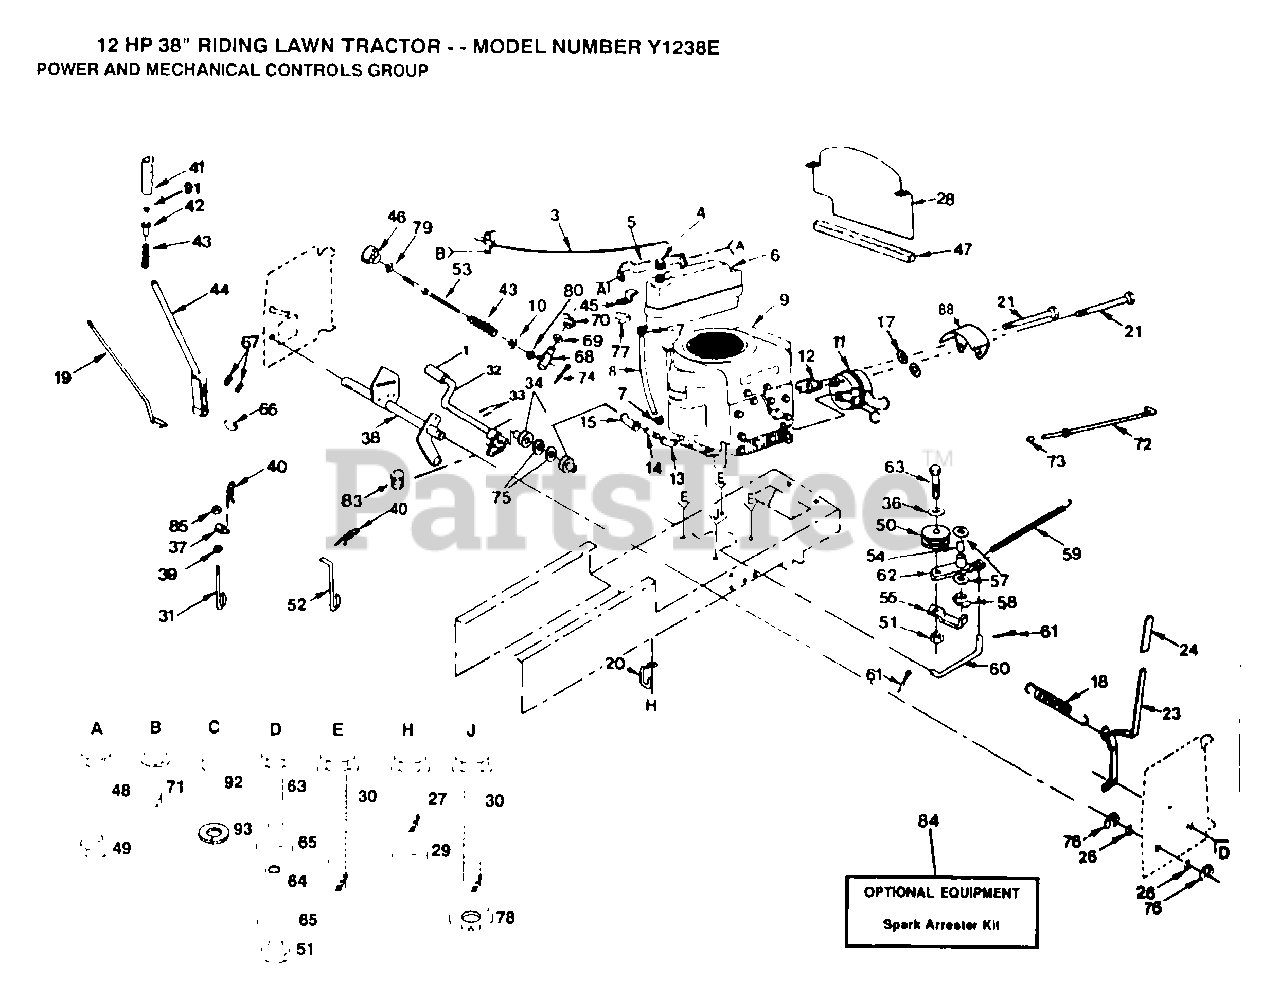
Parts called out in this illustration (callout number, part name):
1	PEDAL COVER T
5	SUPT TANK FUEL
6	FUEL TANK
7	HOSE CLAMP
8	HOSE T
9	ENGINE BRIGGS AND STRATTON
10	WASHER
11	MUFFLER
13	STREET ELBOW LT
14	PIPE NIPPLE
15	ELBOW
18	"SPRING.EXT.8.5"""
19	ROD ASS'Y LEVER
21	BOLT
26	WASHER
27	SCREW
29	WASHER
30	SCREW LT
31	PIVOT PIN T
34	NYLON BEARING
36	WASHER
39	NUT
41	GRIP
43	SPRING T
45	BRACE-TANK LT
46	HDLE ADJ LIFT
48	BOLT
52	LIFT LINK LT
53	ROD LIFT LT
54	"LY, BEARING"
55	RETAIN BELT
57	WASHER LT
58	KLIP RING
59	"SPRING, RETURN LT"
60	"LINK, CLUTCH T"
61	COTTER PIN
62	ARM IDLER
68	TRUNION LT
69	WASHER
70	KLIP RING
71	SCREW LT
72	ROD BRAKE PARK
73	PLUNGER CAP T
75	WASHER LT
76	E-RING
77	PAD-SPACER T
78	LOCKWASHER
79	NUT
80	NUT T
84	SPARK ARREST KIT
88	HEAT SHIELD
92	BOLT
93	LOCKWASHER
